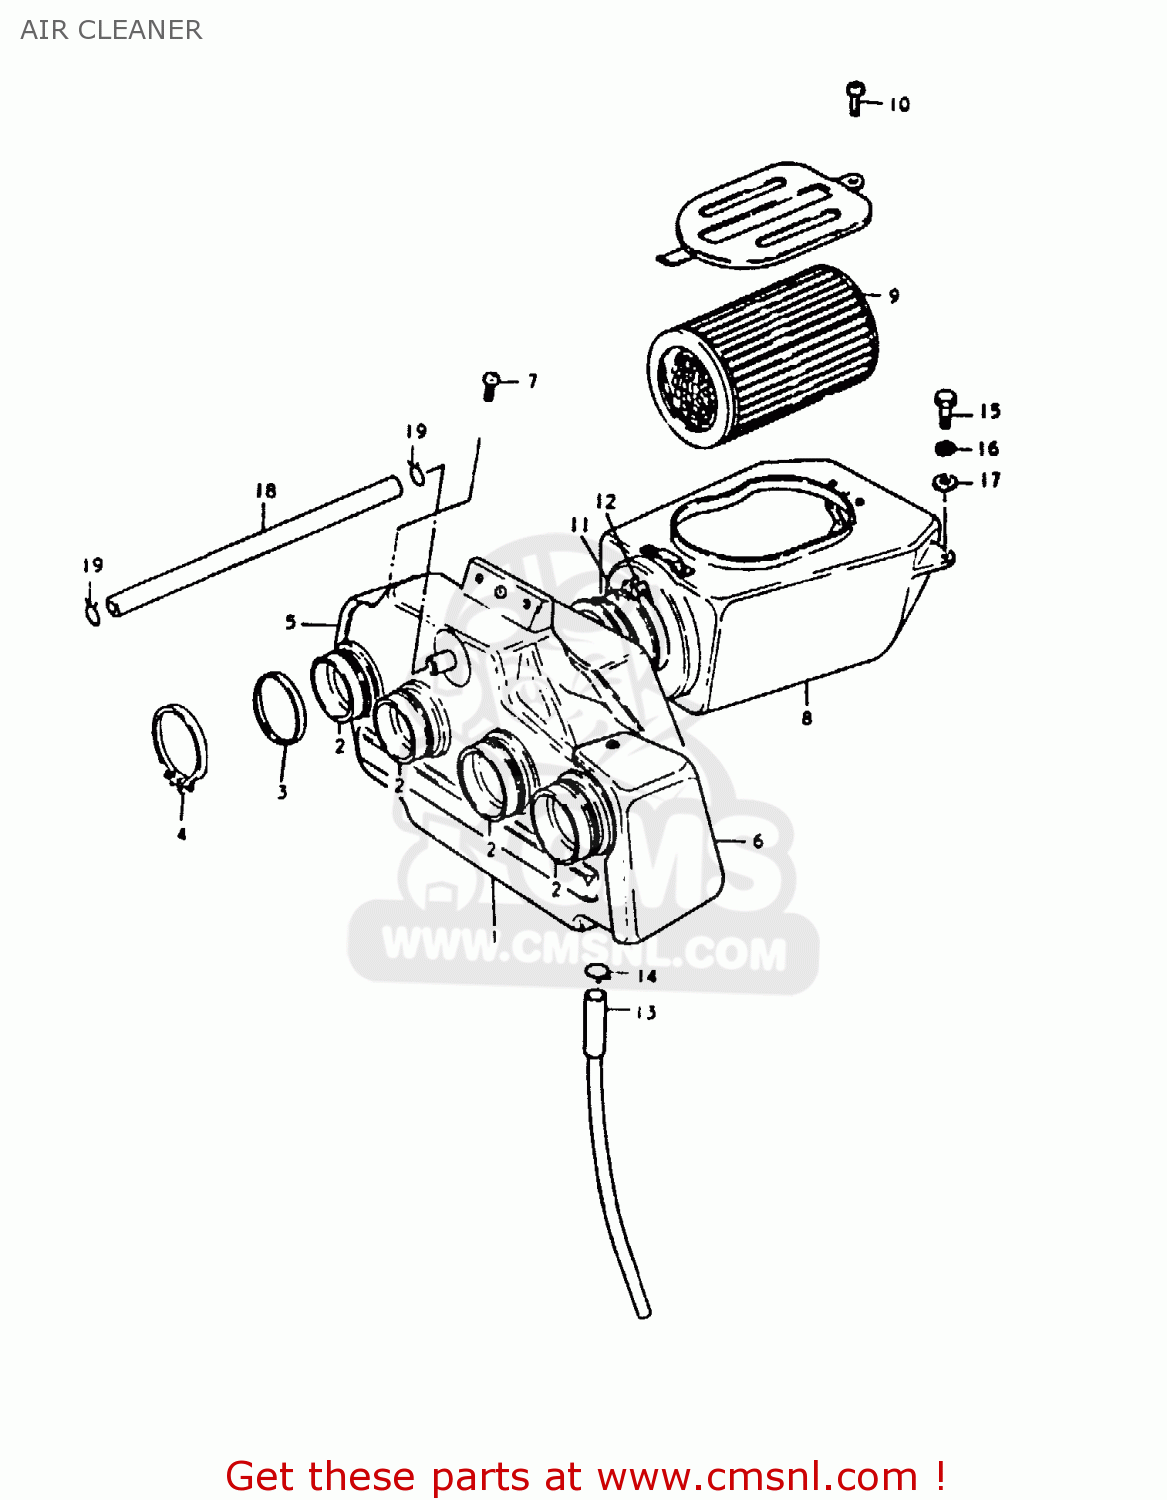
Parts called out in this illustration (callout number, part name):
1	CASE,AIR CLEANER,FRONT
2	TUBE,AIR CLEANER OUTLET
3	RING,CARBURETOR AIR IN
4	CLAMP
5	COVER,CASE,RIGHT
6	COVER,CASE,LEFT
7	SCREW
8	CASE ASSEMBLY,AIR CLEANER
9	FILTER,AIR CLEANER
10	SCREW
11	HOSE,AIR CLEANER
12	BAND
13	DRAIN TUBE
14	CLIP
15	BOLT, UPPER
16	LOCK WASHER
17	WASHER
18	HOSE
19	CLIP
